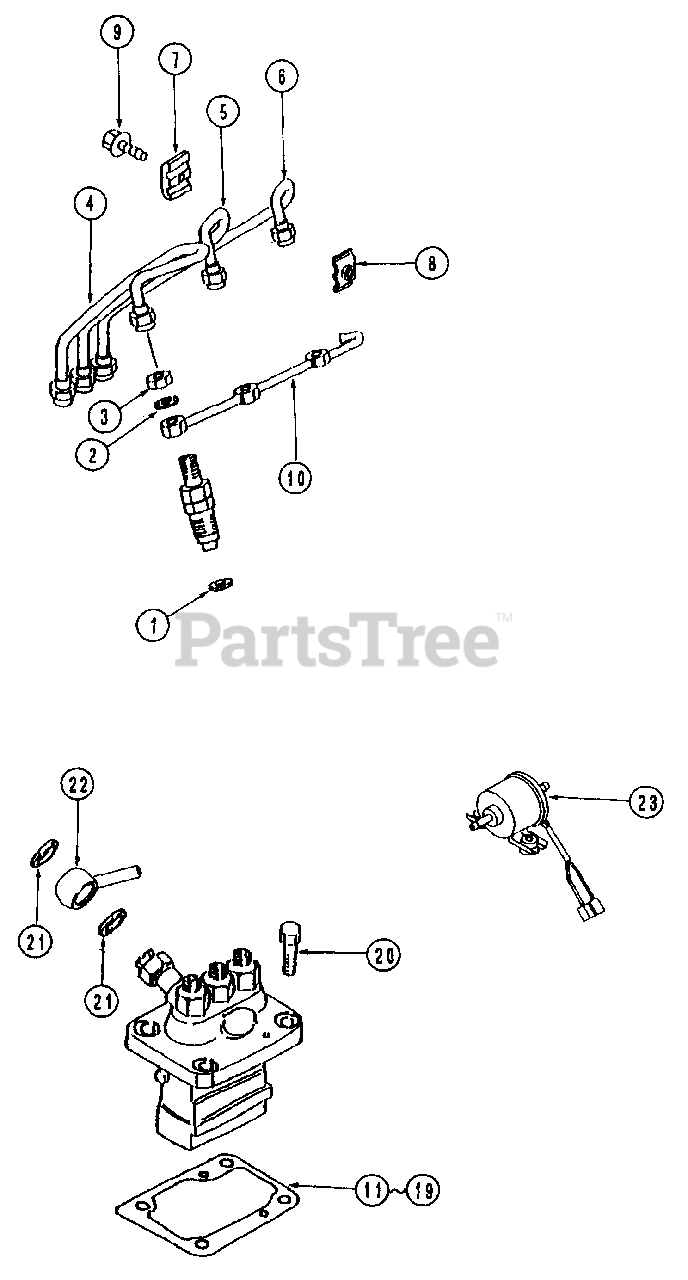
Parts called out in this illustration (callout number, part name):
1	Gasket, Holder
2	Gasket,Fuel Return
4	Pipe, Inj. No.1
5	Pipe, Inj. No.2
6	Pipe, Inj. No.3
9	Bolt, W/Washer
10	Pipe, Fuel Leak-Off
11	Shim
12	Shim
13	Shim
14	Shim
15	Shim
16	Shim
17	Shim
18	Shim
19	Shim
22	Color, Union
23	Fuel Pump Ass'y.
